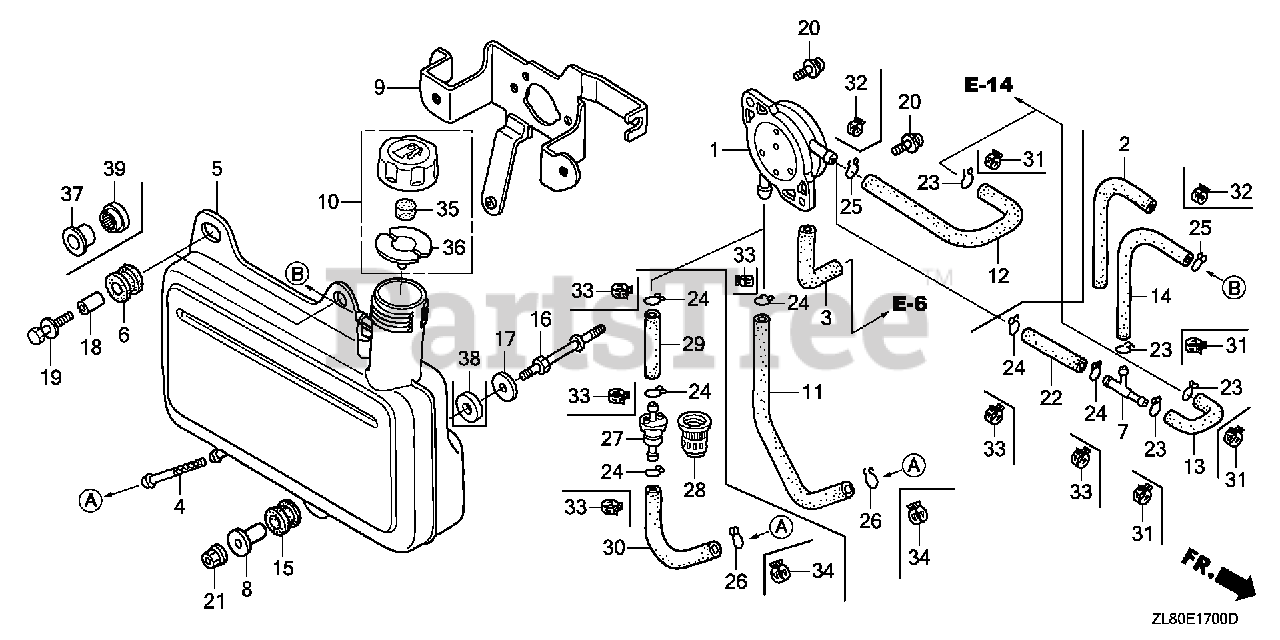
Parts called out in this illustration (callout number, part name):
1	PUMP ASSY., FUEL (MSDS)
2	RUBBER, SUPPORTER (107MM)
3	TUBE, DIAPHRAGM
5	TANK, FUEL
6	RUBBER B, TANK MOUNTING
7	JOINT, FUEL TUBE
8	COLLAR, FUEL TANK SETTING
9	STAY A, FUEL TANK
10	CAP ASSY., FUEL TANK
13	TUBE, FUEL
14	TUBE, FUEL RETURN
15	CUSHION, RR. FENDER
16	BOLT, FUEL TANK STUD (H=30MM)
17	WASHER (6MM)
18	COLLAR (14X6.1)
19	BOLT-WASHER (6X25)
20	SCREW-WASHER (5X14)
21	NUT, FLANGE (6MM)
22	TUBE, FUEL (5.3X33) (FKM) (NOT AVAILABLE)
22	BULK HOSE, FUEL (5.5X3000) (5.3X33)
23	CLIP, TUBE (B8)
24	CLIP, TUBE (B10)
25	CLIP, TUBE (C9)
26	CLIP, TUBE (C11)
27	FILTER, FUEL
28	SUSPENSION, STRAINER
29	TUBE, FUEL PUMP
30	TUBE, FUEL TANK
30	TUBE, FUEL TANK (FKM) (NOT AVAILABLE)
31	CLAMP, TUBE (D8)
32	CLAMP, TUBE (D8.5)
33	CLAMP, TUBE (D10)
34	CLAMP, TUBE (D12)
35	SPONGE, FUEL CAP BREATHER
36	GASKET, FUEL CAP
